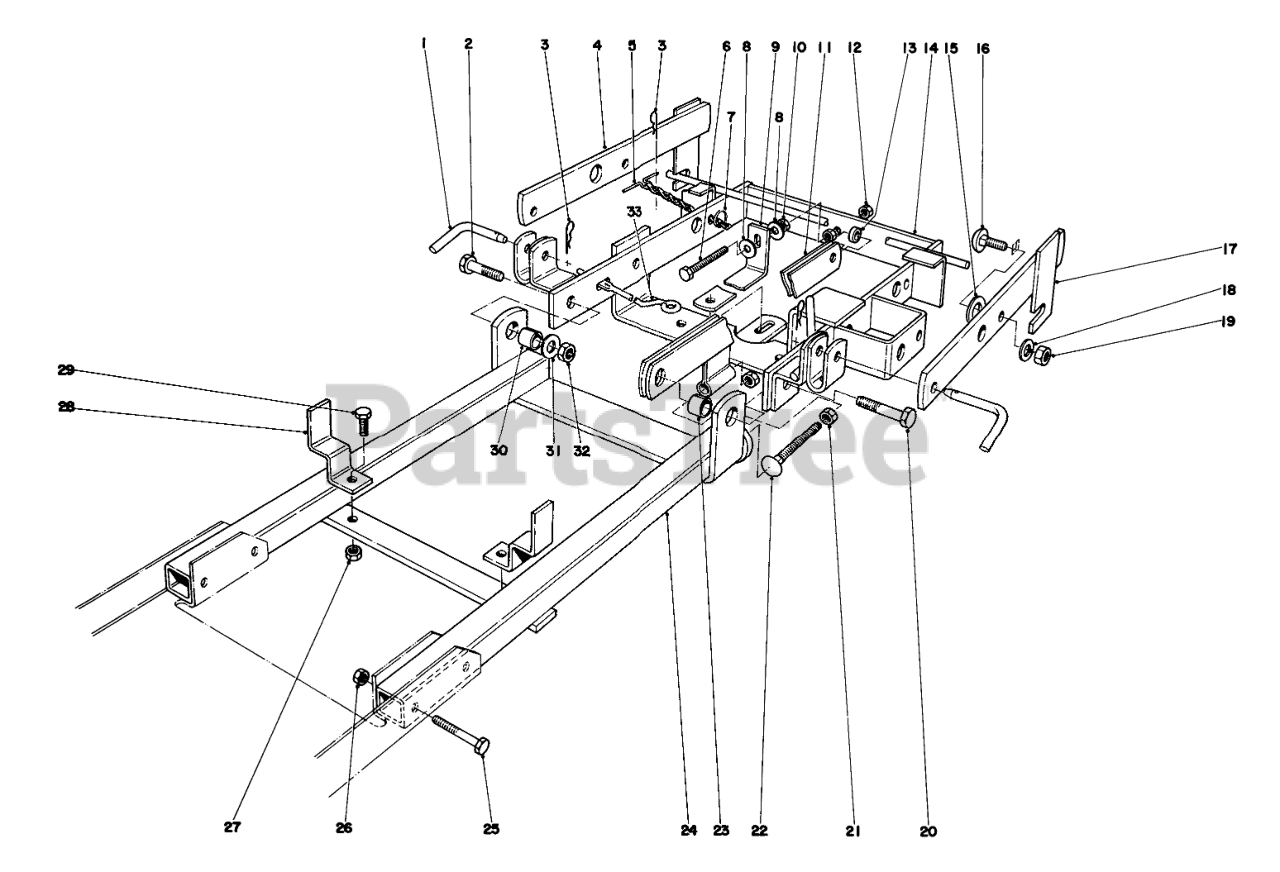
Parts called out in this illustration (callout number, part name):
1	Pin-Roller, Locating
2	SCREW-HH
3	TINNERMAN NUT
4	MountingBracket-R.H.
5	Chain & Toggle
6	SCREW-HH
7	Spring Clip
8	WASHER-FLAT
9	Bracket-Belt Adjust
10	NUT-JAM
11	Lift Extension
12	NUT-HEX
13	Spacer
14	Mounting Frame-Upper
15	Washer-Flat
16	Carriage Bolt
17	Mounting Bracket-L.H.
18	WASHER-LOCK
19	NUT-HEX
20	SCREW-HH
21	NUT-JAM
22	Carriage Bolt
23	Spacer-Bearing
24	Mounting Frame
25	SCREW-HH
26	NUT-LOCK, CONE
27	NUT-LOCK, CONE
28	Stop-Position
29	SCREW-HH
30	Spacer-Idler Pulley
31	WASHER-FLAT
32	1/2-13 CONELOCK NUT
33	Wire-Belt Guide
